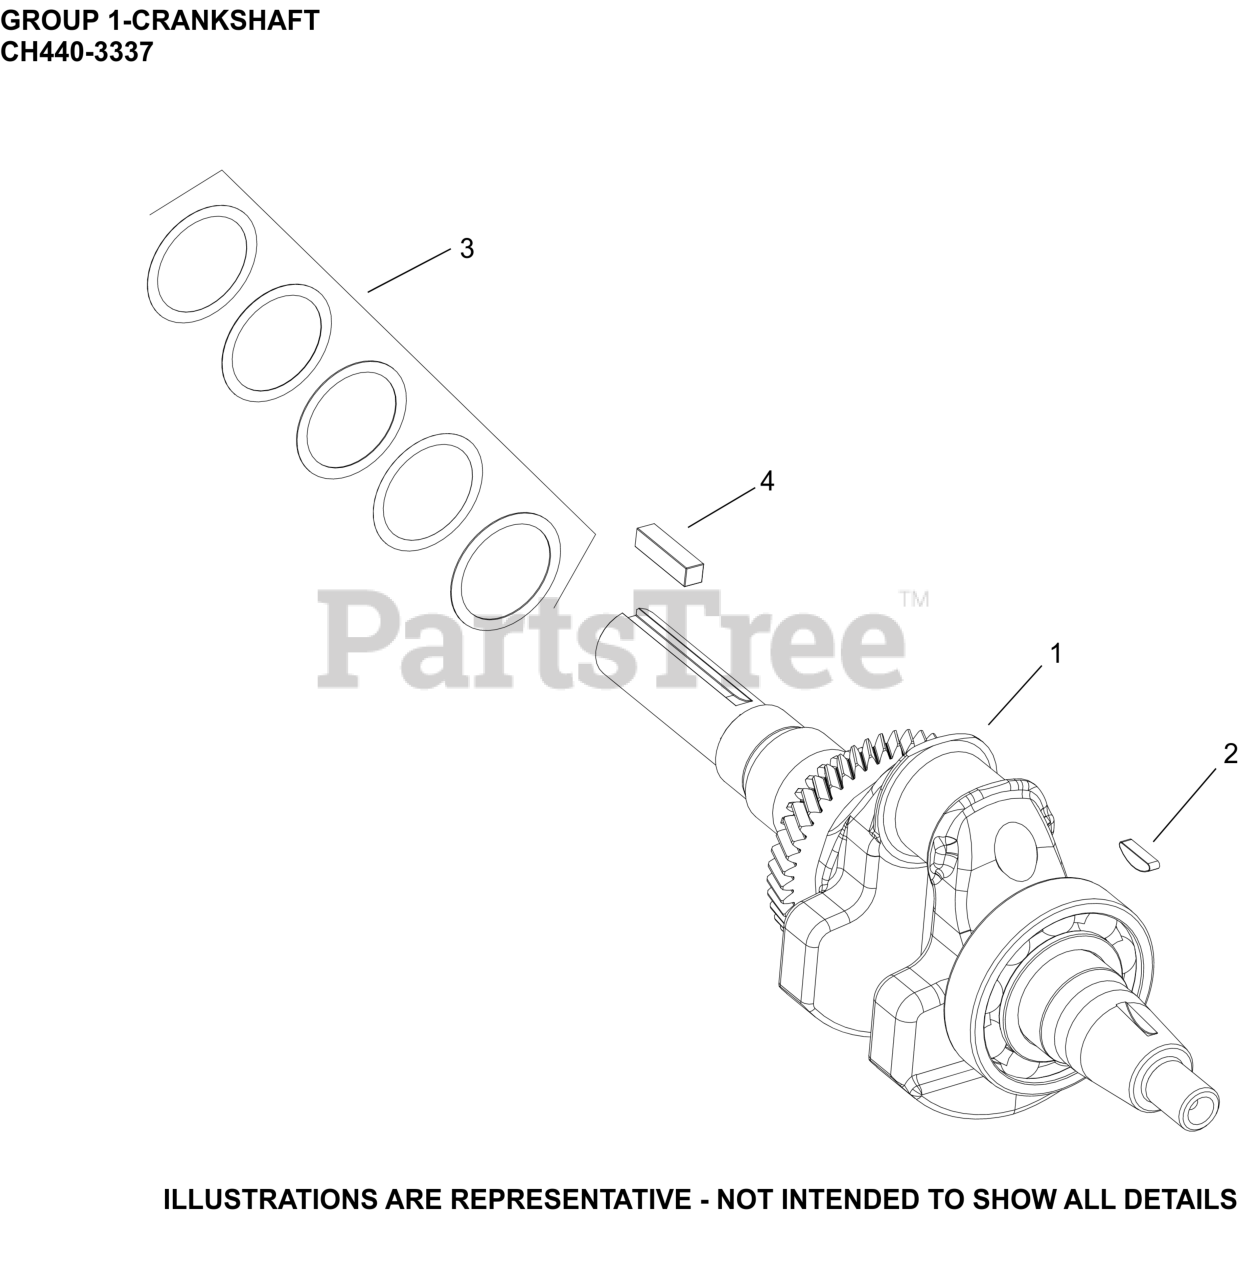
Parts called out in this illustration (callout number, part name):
1	CRANKSHAFT ASSEMBLY
2	KEY, FLYWHEEL
3	KIT, SHIM
4	KEY, SQUARE
